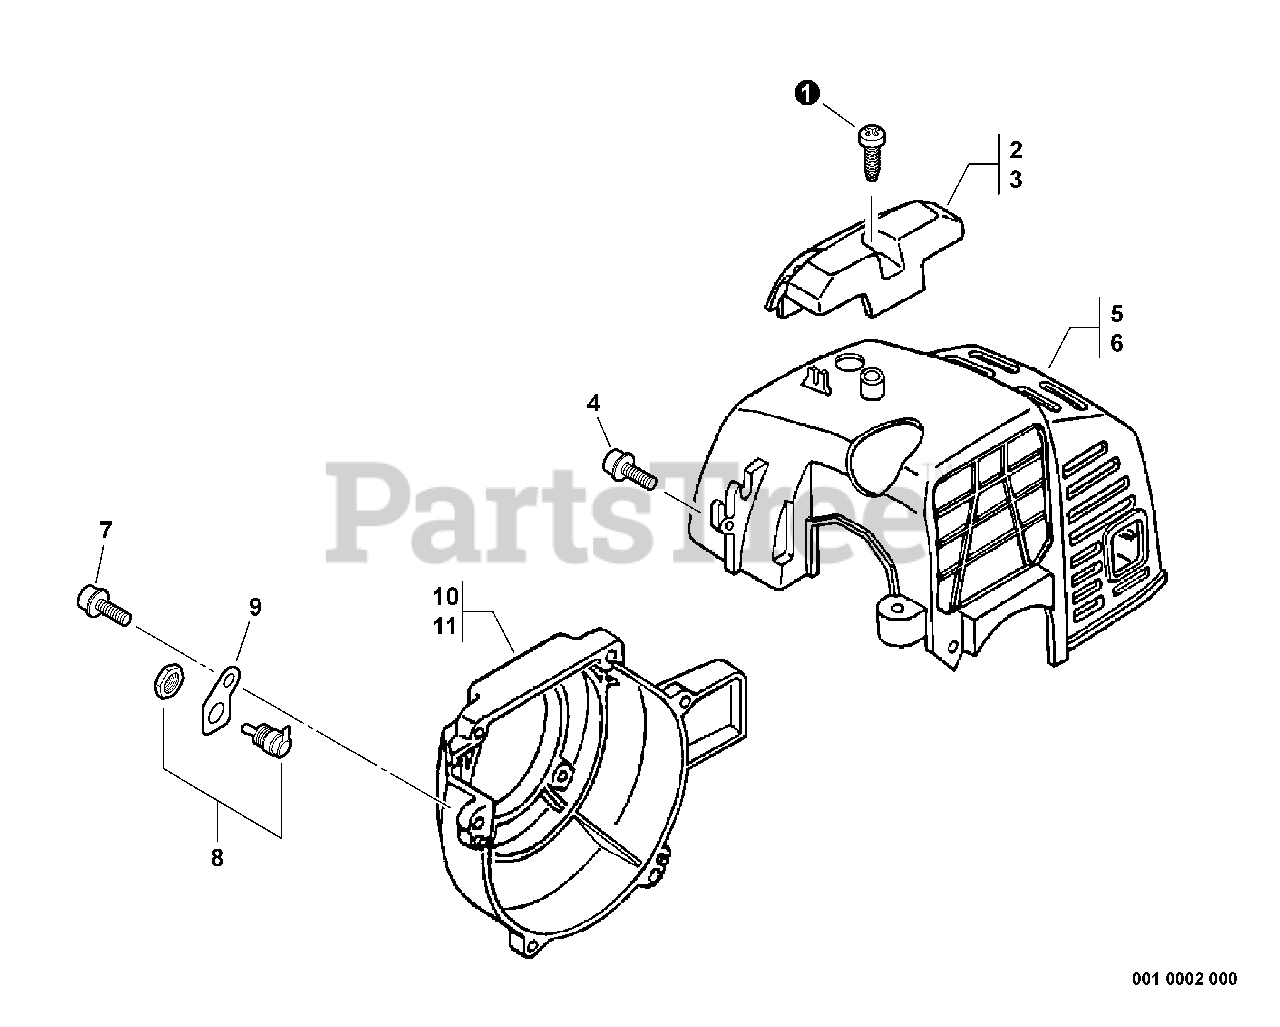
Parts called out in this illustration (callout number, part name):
1	SCREW - 5X16 -- TAPPING
2	GUARD, TOP - GRAY
3	GUARD, TOP - BLACK
4	SCREW - 4X12
5	COVER, ENGINE - GRAY
6	COVER, ENGINE - ORANGE
7	SCREW - 4X16
8	IGNITION SWITCH ASSY
9	BRACKET, SWITCH
10	CASE, FAN - GRAY
11	CASE, FAN - ORANGE
